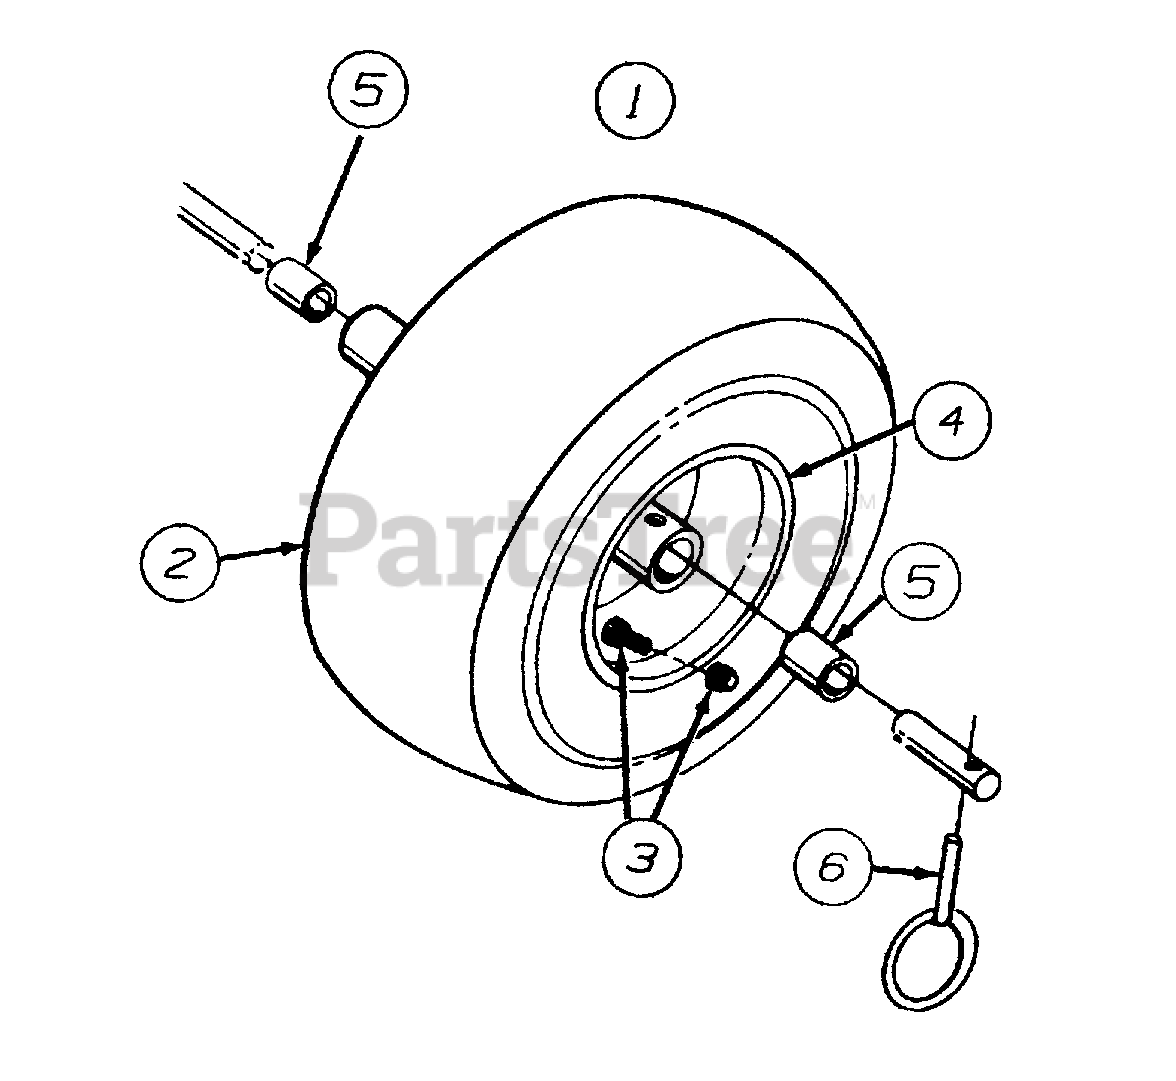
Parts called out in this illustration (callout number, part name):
1	Wheel Ass'y. Complete
3	Air Valve
4	Rim Only
5	Sleeve Bearing
6	Klick Pin (2)
